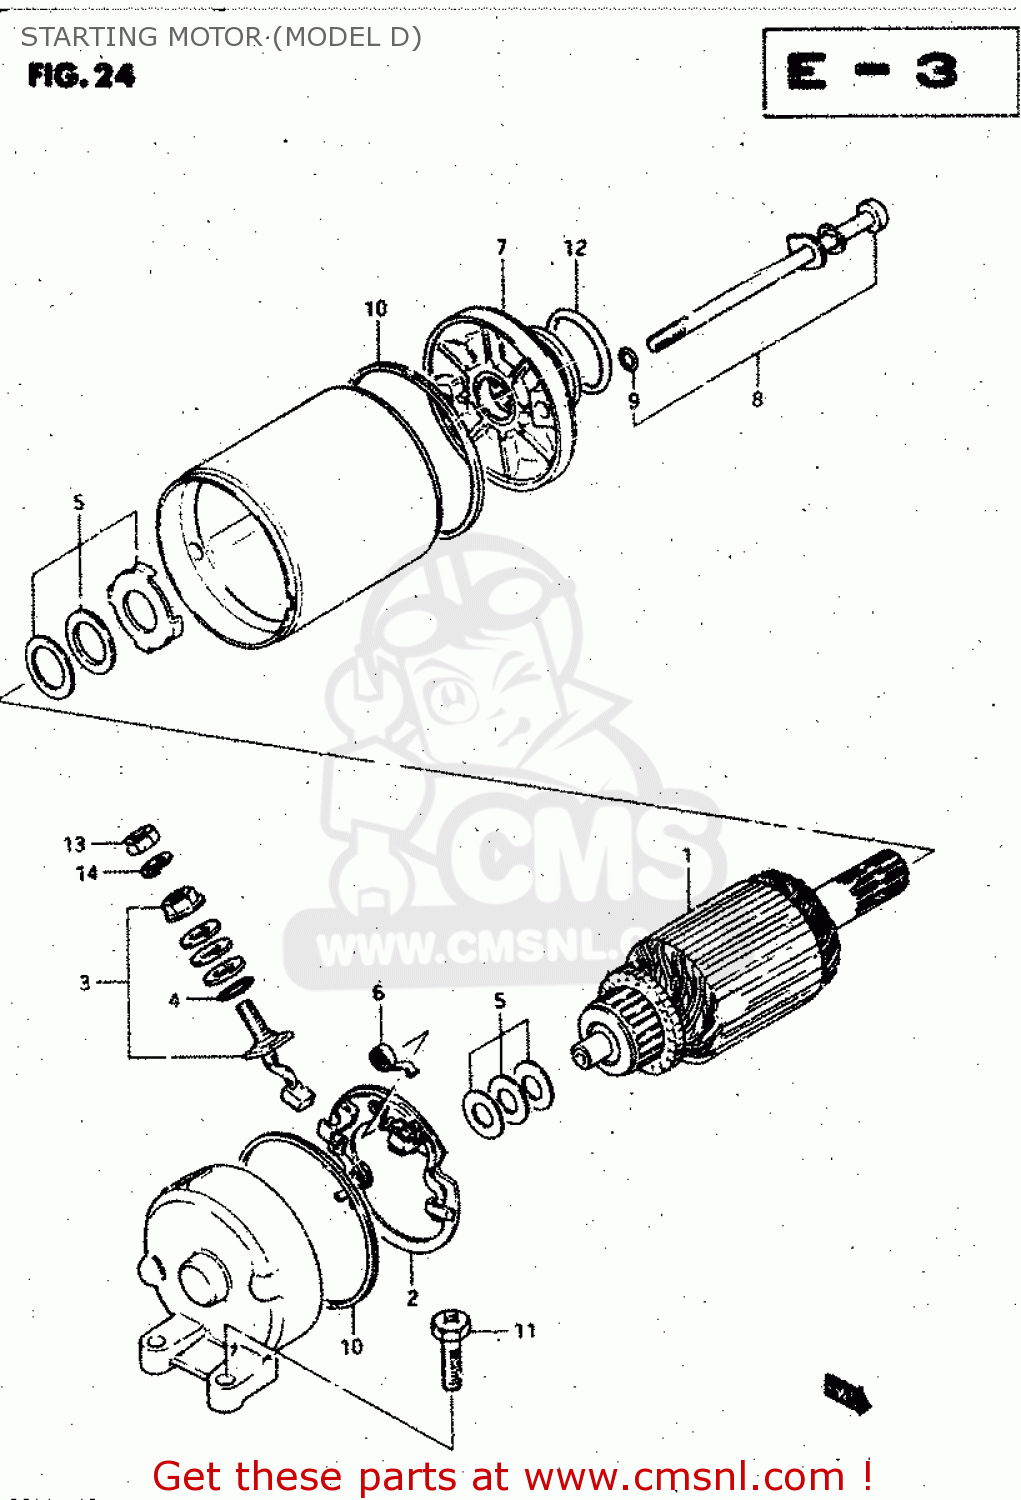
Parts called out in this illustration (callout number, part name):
1	ARMATURE
2	HOLDER SET,BRUSH(-)
3	TERMINAL SET,BRUSH,PLUS
4	O RING
5	SHIM SET,STARTING MOTOR
6	SPRING,BRUSH
7	BRACKET SET,STARTING MOTOR
8	BOLT SET,STARTING MOTOR
9	O RING
10	O RING
11	SCREW (6X25)
12	O RING(D:2,ID:24.5)
13	NUT 6MM
14	LOCK WASHER
